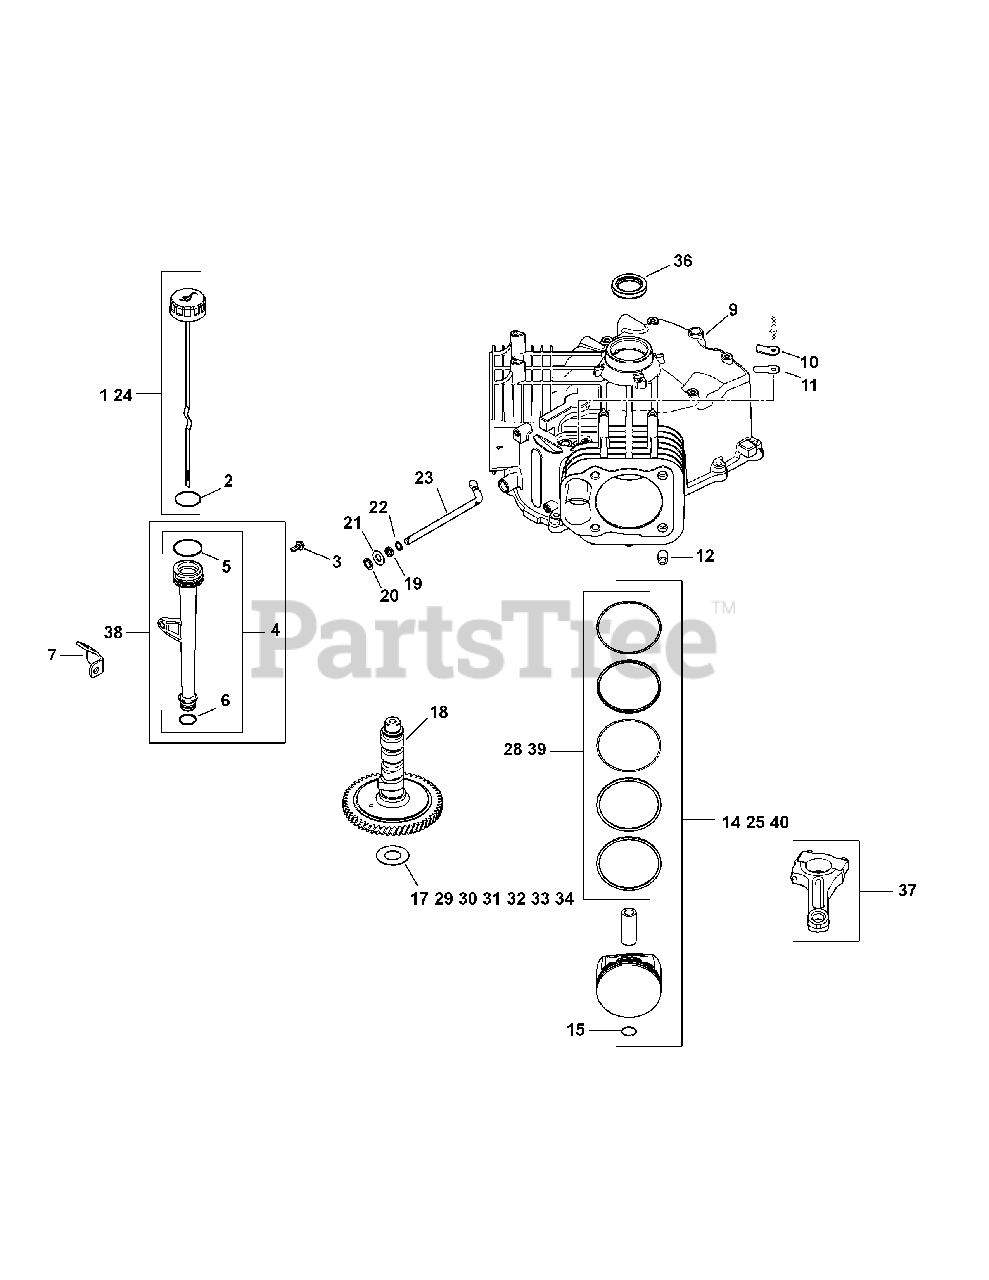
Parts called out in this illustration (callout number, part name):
1	Dipstick (Inc. 2)
2	Dipstick O-Ring
3	Flg. Thd. Frm. Screw, M5 x 0.8 x 13
4	Fuse Block
5	Fuse Block
6	Fuse Block
7	Oil Fill Tube Bracket
9	Fuse Block
10	Breather Reed Retainer
11	Breather Reed
12	Use KH-24-380-16-S Pin
14	Piston w/ Ring Set Kit (Inc 15 & 16)
15	Piston Pin Retainer
17	Camshaft Shim (White .028")
18	Camshaft Kit (Inc. KH-25-357-14-S)
19	Governor Cross Shaft Seal
20	Ring Retainer
21	Flat Washer, 9mm
22	Flat Washer, 11.32
23	Governor Cross Shaft
24	Dipstick Assembly
25	Piston w/ Ring Set Kit (0.25) 83mm
28	Use KH-24-108-16-S Ring Set
29	Camshaft Shim (Blue .03")
30	Camshaft Shim (Red .032")
31	Camshaft Shim (Yellow .034")
32	Camshaft Shim (Green .036")
33	Camshaft Shim (Gray .038")
34	Camshaft Shim (Black .04")
36	Oil Seal (Helix Lip)
37	Connecting Rod (Std)
38	Tube Assembly (Inc. 4-6)
39	Ring Set (Std)
40	Use KH-24-874-27-S Kit
